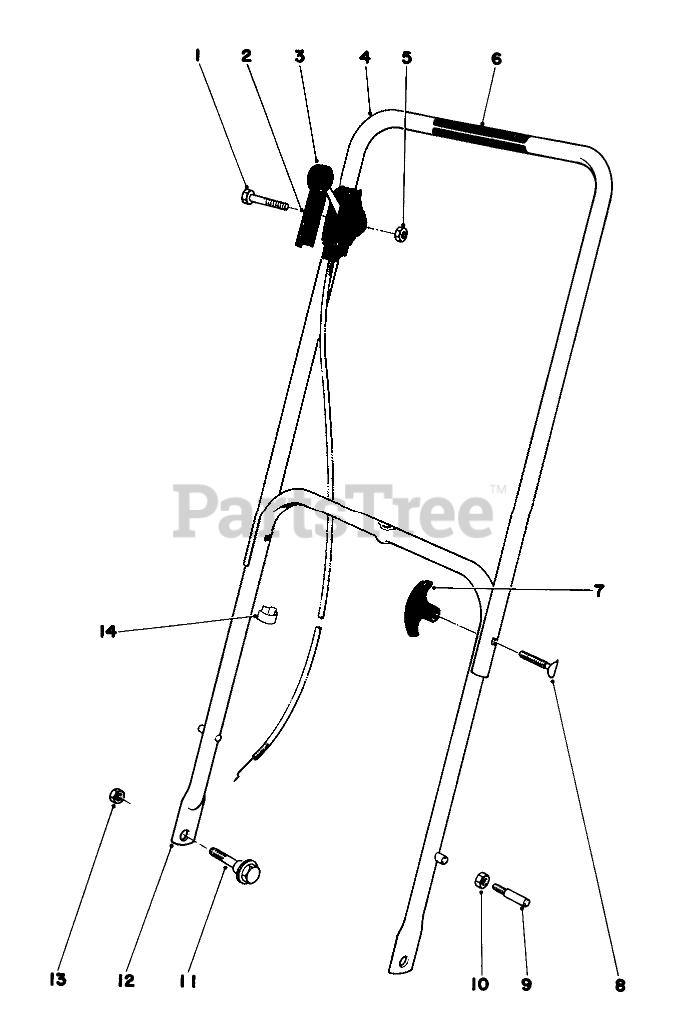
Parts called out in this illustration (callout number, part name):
1	SCREW-HH
2	Decal Throttle Control
3	Throttle Control
4	Upper Handle
5	NUT-LOCK
6	Decal Danger (French & Dutch)
8	HANDLE SCREW
9	HANDLE PIN
10	Nut
11	SCREW-SHOULDER
12	19 LOWER HANDLE ASM
13	Nut
14	BOWDEN CLIP
